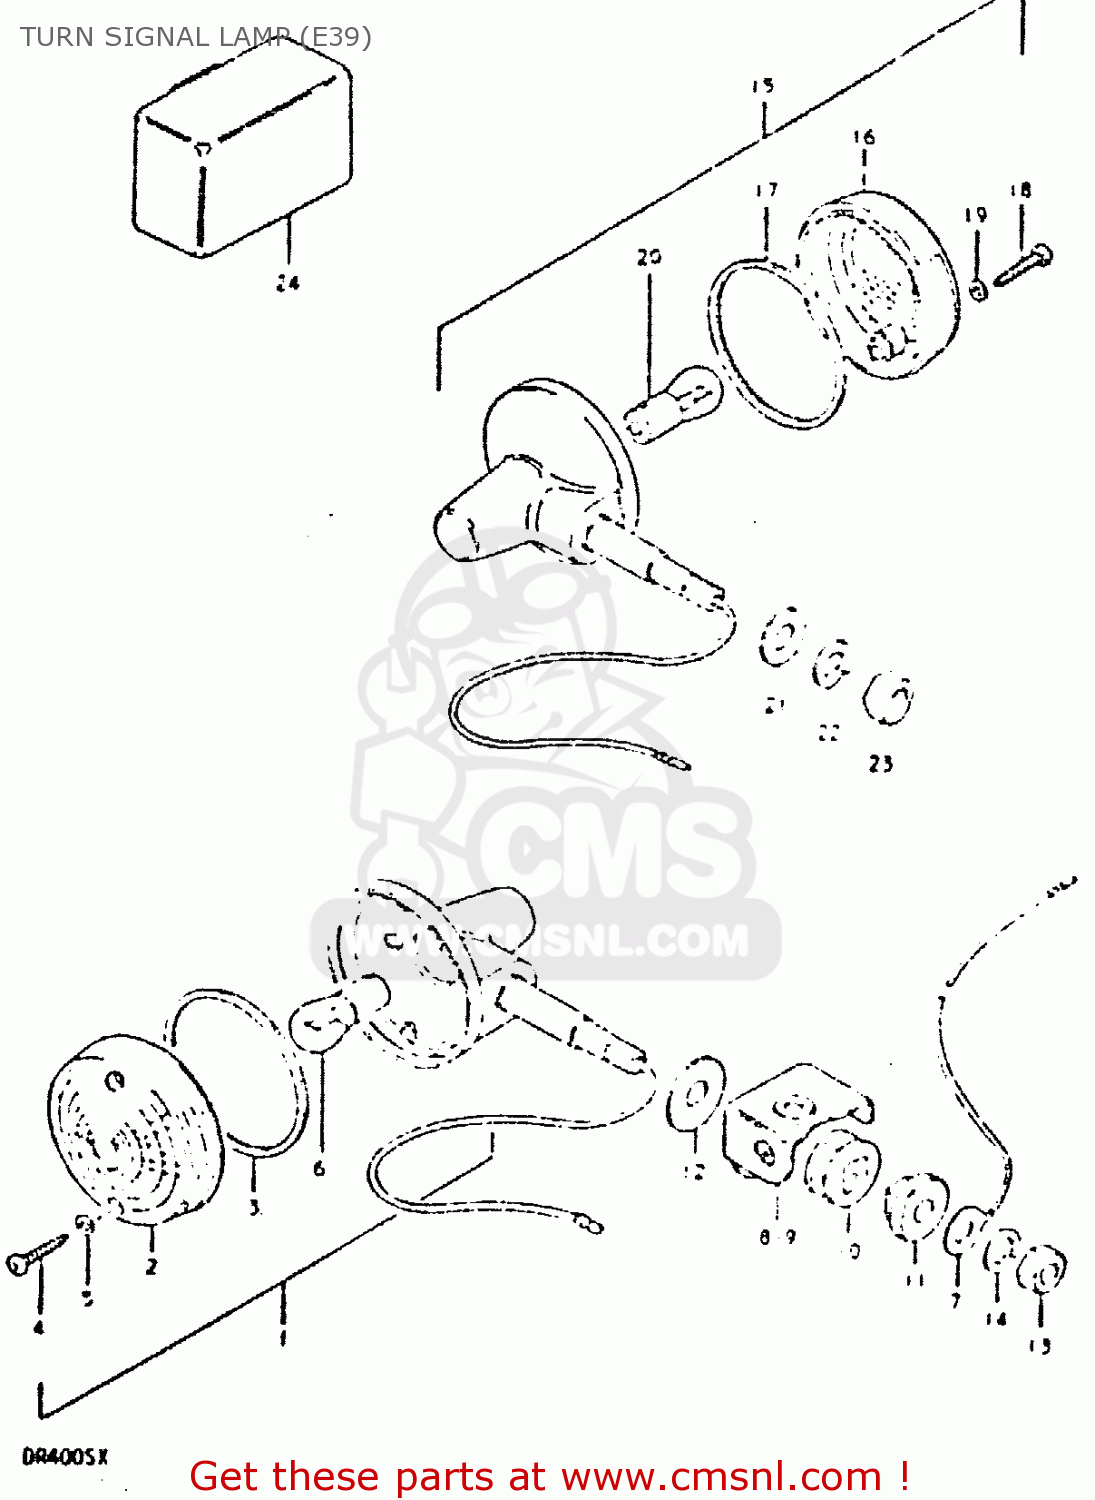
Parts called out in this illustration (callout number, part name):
1	LAMP, FRONT TURN SIGNAL
2	LENS
3	GASKET
4	SCREW
5	GASKET (NAS)
6	BULB (6V,21W)
7	LEAD WIRE,EARTH
8	BRACKET, FRONT RH
9	BRACKET, FRONT LH
10	CUSHION
11	SPACER,TURN SIGNAL LAMP
12	WASHER (10.5X30X2.3)
13	NUT
14	LOCK WASHER
15	LAMP, REAR TURN SIGNAL
16	LENS
17	GASKET (NAS)
18	SCREW
19	GASKET (NAS)
20	BULB (6V,21W)
21	WASHER
22	LOCK WASHER
23	NUT
24	RELAY, TURN SIGNAL
